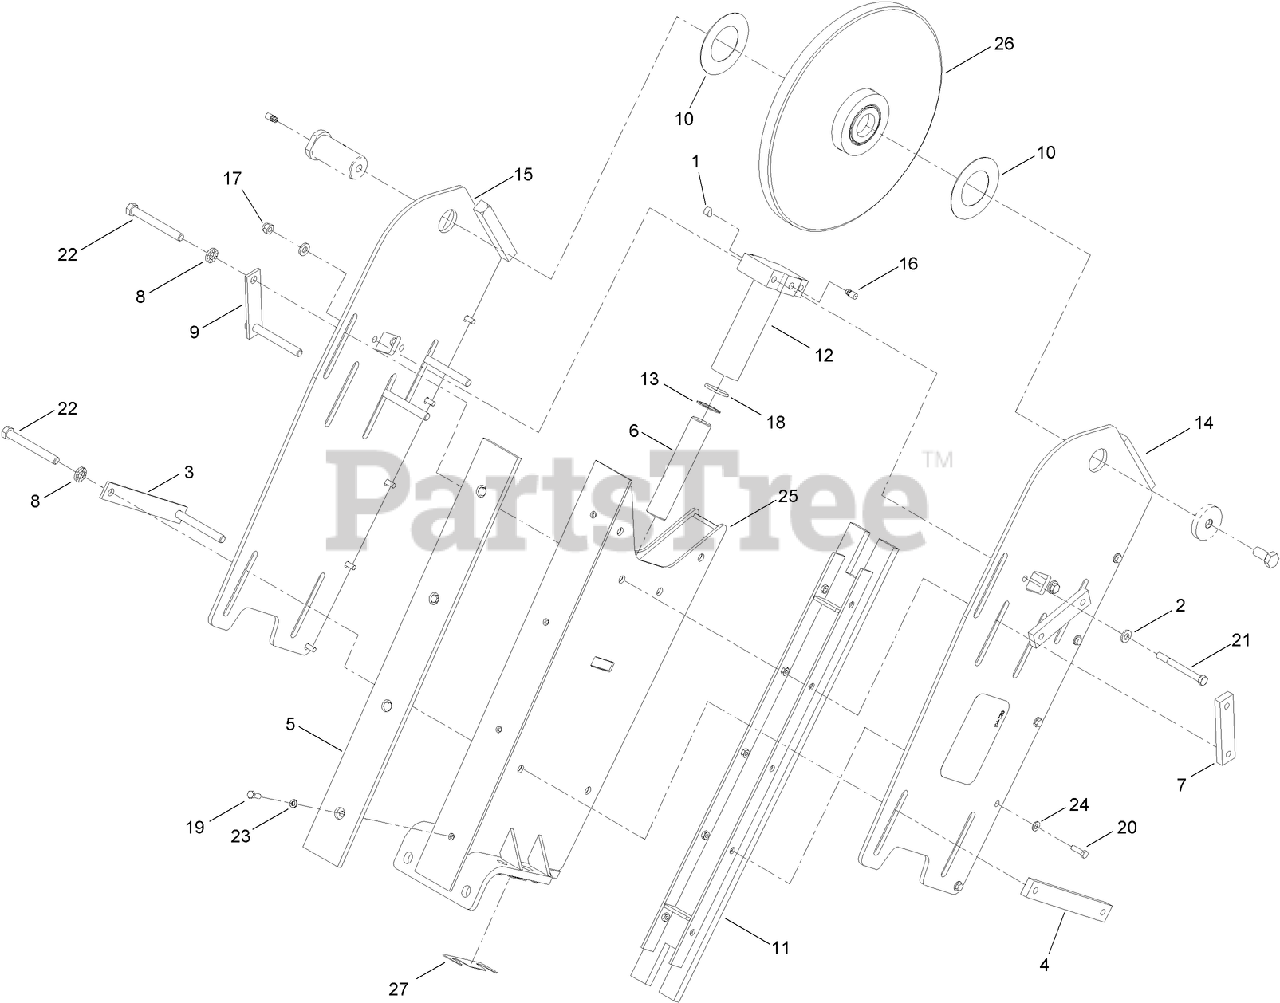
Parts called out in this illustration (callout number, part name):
1	PLUG-BLEED
3	BAR-WASHER, LONG
4	BAR-TAPPED, LONG
5	BAR-WEAR PAD, 4 FT.
6	ROD-BOOM, END (CYLINDER)
7	BAR-TAPPED, SHORT
8	WASHER-LOCK
9	BAR-WASHER, SHORT
10	WASHER-BOOM, END (ROLLER)
11	CHANNEL-WEAR PAD, 4 FT
12	CYLINDER ASM (BOOM END)
13	WASHER-BACKUP
14	LH END BOOM PLATE ASM
15	RH END BOOM PLATE ASM
16	FITTING-LUBE, STRAIGHT
17	NUT-HEX
19	SCREW-HH
20	SCREW-HH
22	SCREW-HH
23	WASHER-LOCK
24	WASHER-FLAT
25	BOOM-ROCK, 4 FT
26	BOOM END ASM
